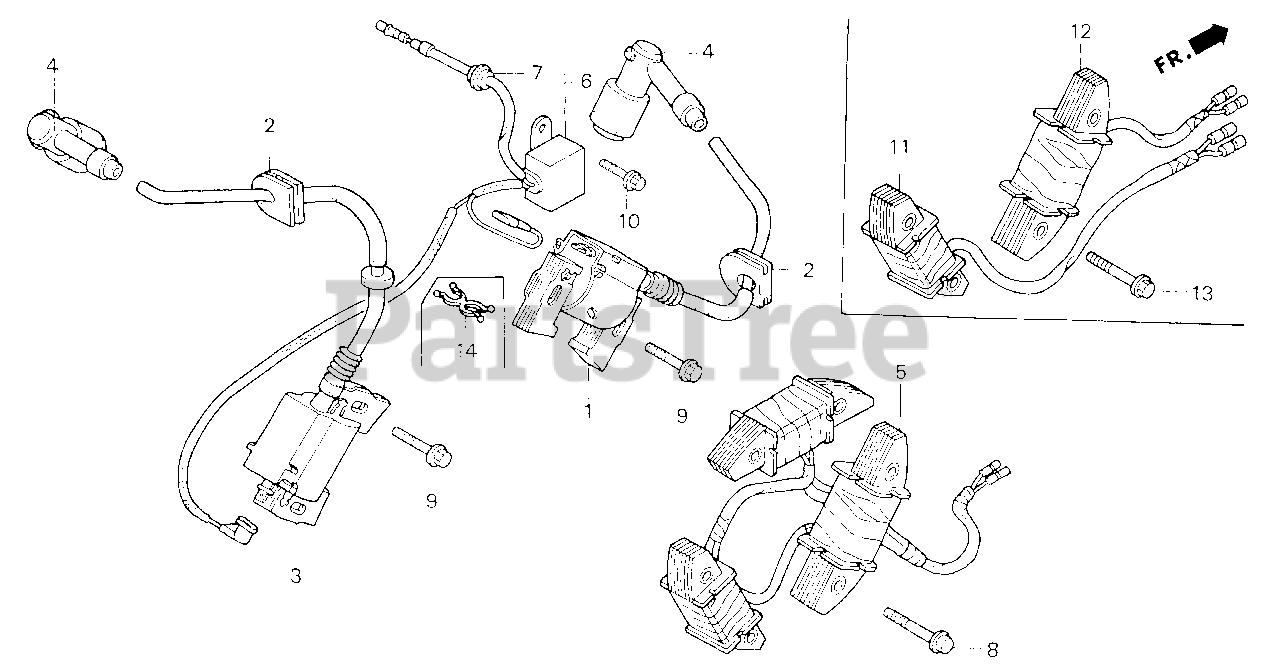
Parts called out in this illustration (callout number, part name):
1	COIL ASSY., R. IGNITION
2	GROMMET, IGNITION WIRE
3	COIL ASSY., L. IGNITION
4	CAP ASSY., NOISE SUPPRESSOR
5	COIL ASSY., CHARGE (12V/20A)
6	DIODE ASSY., ENGINE STOP
7	GROMMET, TOOL
8	BOLT, FLANGE (6X32)
9	BOLT, FLANGE (6X25)
10	BOLT, FLANGE (6X8)
